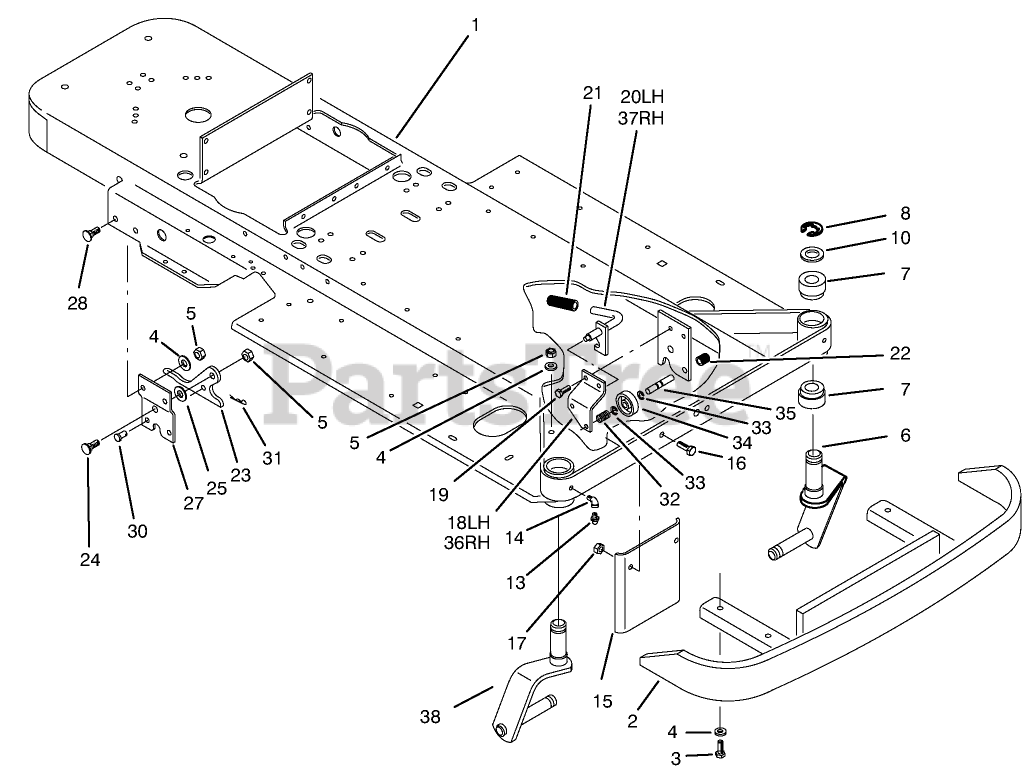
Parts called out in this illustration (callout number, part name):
1	Frame
2	Bumper-Front
3	SCREW-HH
4	WASHER-FLAT
5	NUT-LOCK, NI
6	Fork-Front Wheel, LH
7	BUSHING PIVOT
8	RING-RETAINING
10	Washer
13	FITTING-GREASE
14	ELBOW
15	Shield
16	SCREW-HH
17	NUT-LOCK, NI
18	Bracket LH
19	SCREW-HWHTF
20	Latch LH
21	GRIP
22	CAP-ROD, PLUNGER
23	PLATE-LATCHING
24	BOLT-CARR
25	WASHER
27	Plate-Hitch
28	BOLT-CARR
30	PIN-CLEVIS
31	PIN-HAIR
32	SPRING
33	RING-RETAINING
35	ROD-LOCK
36	Bracket RH
37	Latch RH
38	Fork-Front Wheel, LH
